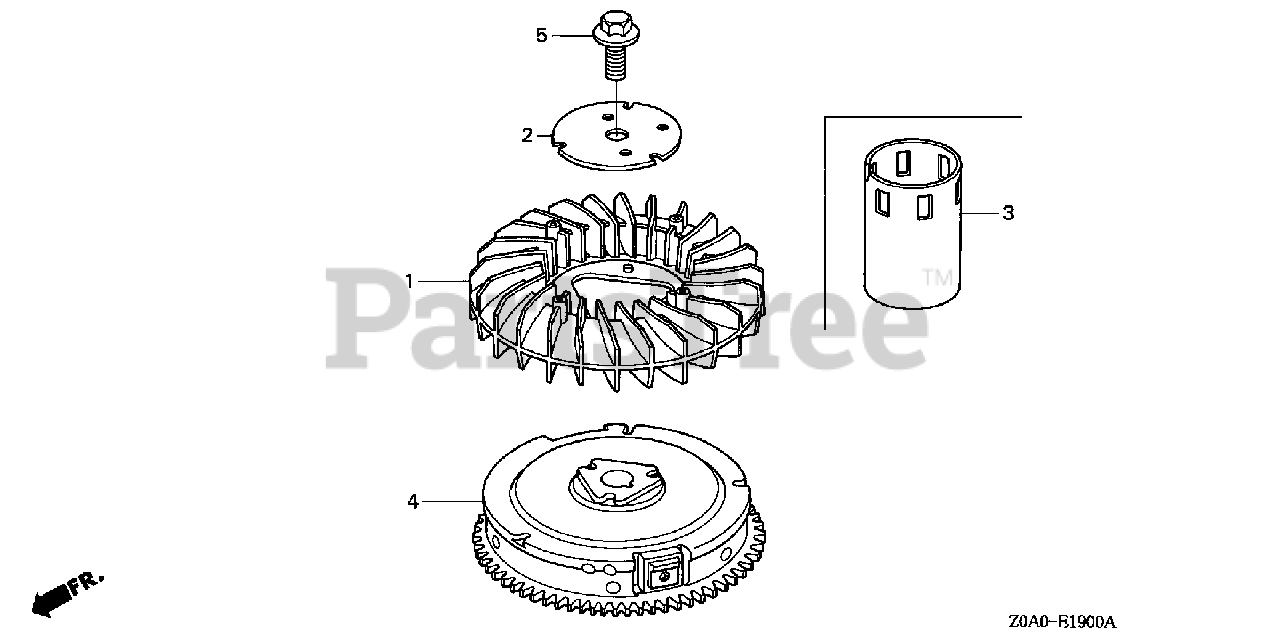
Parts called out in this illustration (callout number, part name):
1	FAN, COOLING
2	PLATE, COOLING FAN SETTING
4	FLYWHEEL (6P)
5	BOLT, FLANGE (16X35)
